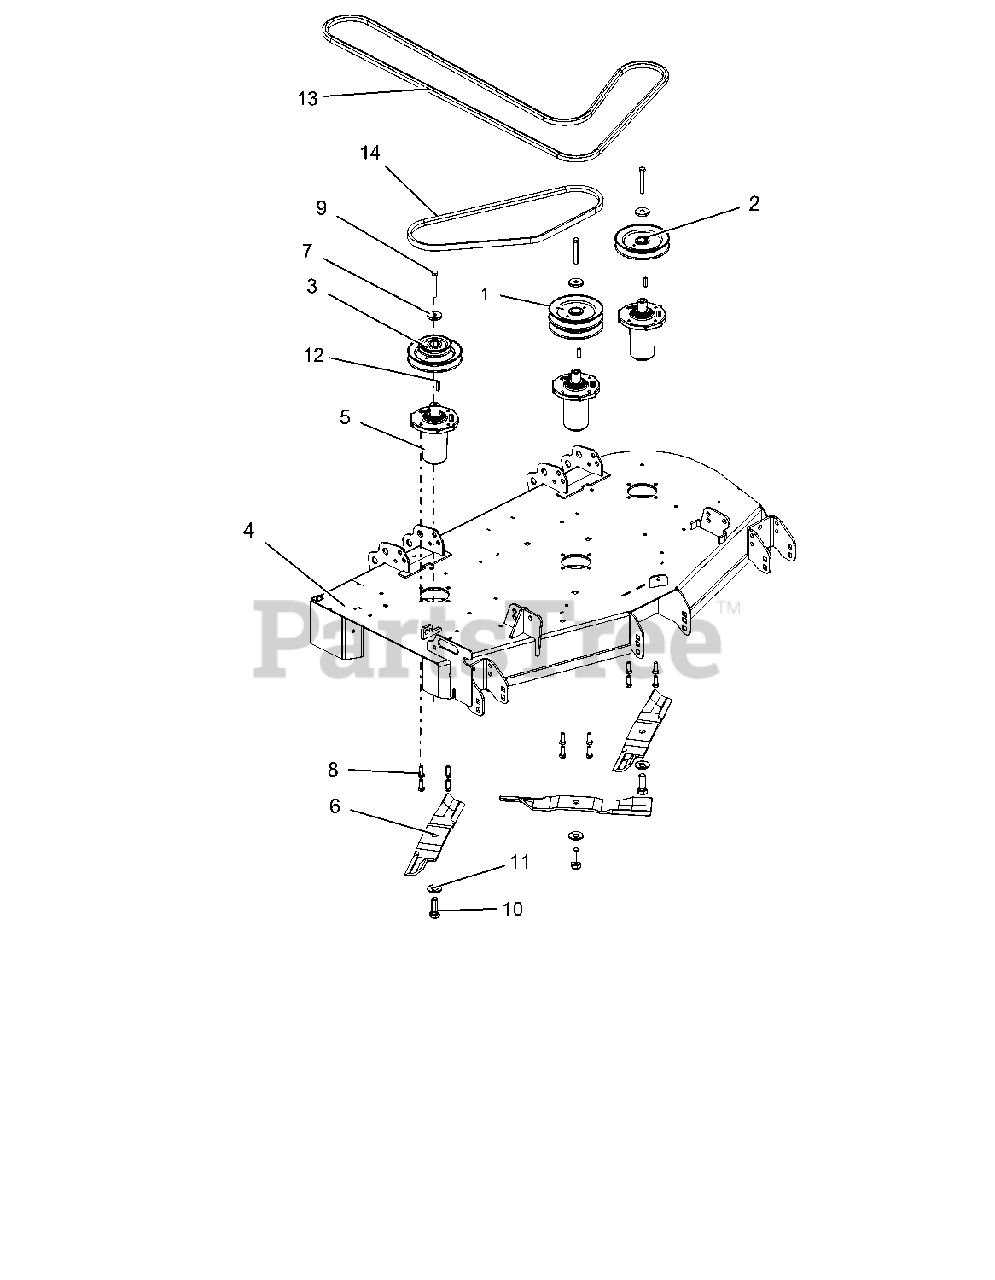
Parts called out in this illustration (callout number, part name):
1	PULLEY, DOUBLE-1" ID X 5.75" OD-BLACK
2	PULLEY, V - 1" ID X 5.75" OD-BLACK
3	PULLEY, DBL -1"IDX5.75"&3.50"OD-BLACK
4	KIT, DECK-48' W/SAFETY DECALS-RED
5	SERVICE, ASM SPINDLE- DUCTILE
6	BLADE, 16.19" MOWER (HI-LIFT)
7	RETAINER, SHEAVE SPINDLE
8	BLT-HEX .38-16X1.00 GR5 YWZC EP30
9	BLT-HEX .38-16X2.75 GR8 YWZC
10	BLT, HEX .62-18X1.75 GR8 YWZC
11	WSHR, BLVL .63X1.625X.14
12	KEY-SQ .250X.250X1.00 RC 40-50
13	V-Belt, BB-Wrapped Clutching
14	V-BELT, B-RAW EDGE COGGED
